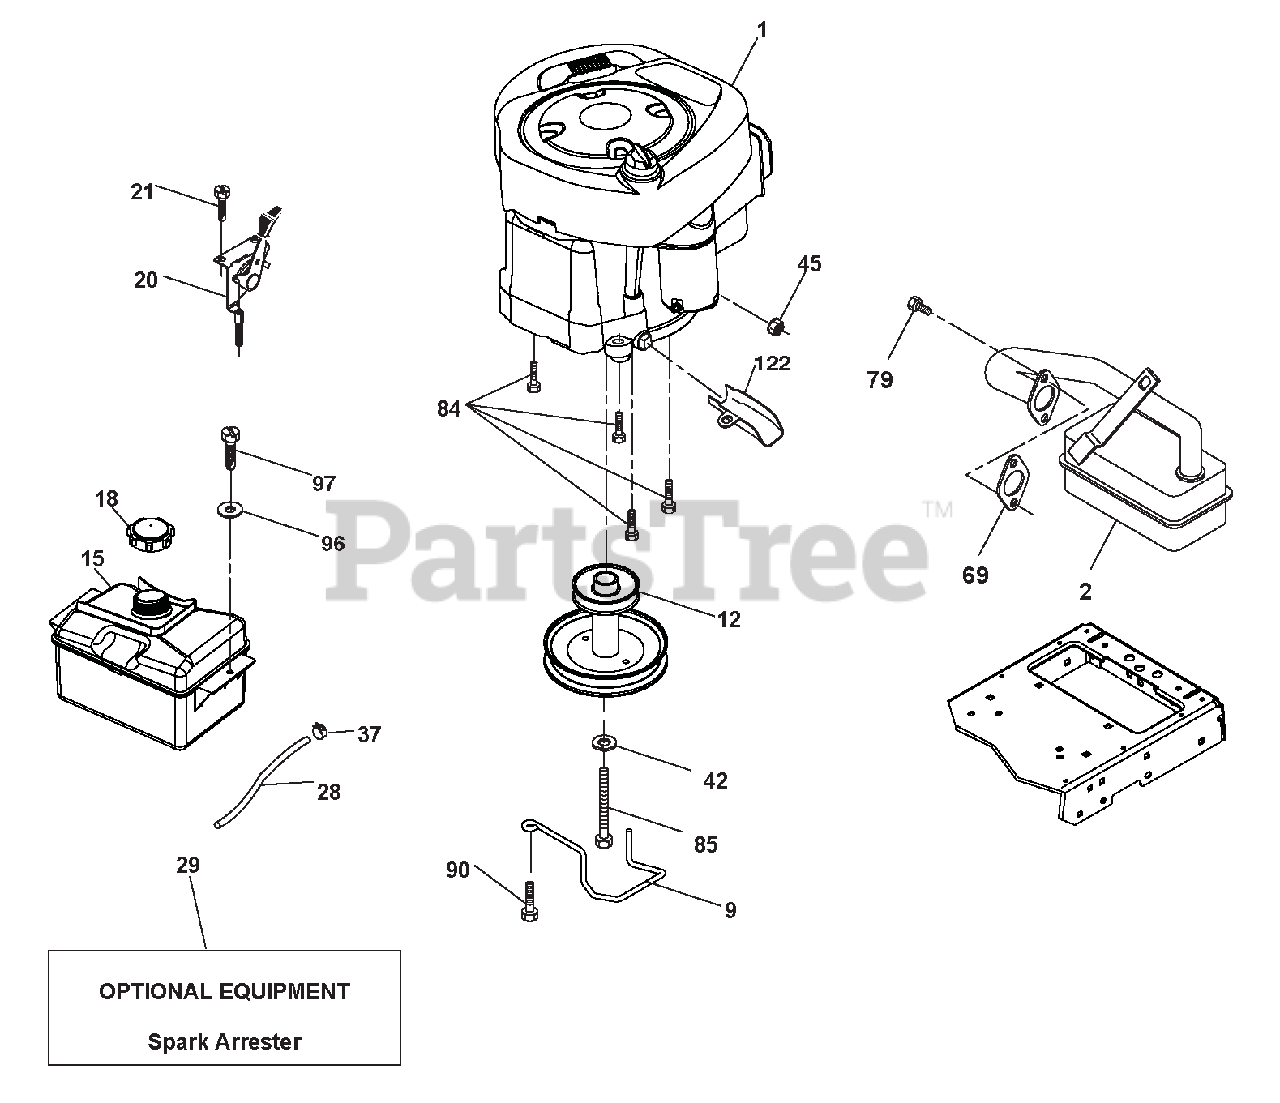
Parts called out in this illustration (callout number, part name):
1	ENGINE BRIGGS MODEL NO. 31P677-1577-G5 (442254)(ORDER PARTS FROM ENGINE MANUFACTURER.)
2	Muffler Exhaust B&S
9	KEEPER BELT ENGINE
12	PULLEY.ENGINE
15	TANK FUEL
18	CAP FUEL
20	CONTROL.THROTTLE
28	LINE.FUEL.20"
29	KIT.SPARK ARRESTOR(392390 B&S)
37	CLAMP.HOSE.BLK.
42	WASHER.LOCK.HVY HLCL.SPR.7/16
45	Nut, Keps Hex 1/4-20 unc
69	Gasket Eng 1 313 Id Tin Plated
79	SCREW.SOCKET HD.5/16-18 X .75
84	Screw 3/8-16 x <
85	BOLT.HEX.7/16-20X4XGR5-1.5THR.
90	SCREW.3/8-16X1.SMGML.TAP/R.BLK
96	WASHER.9/32 X 7/8 X 16GA.
97	SCREW.HEXWSH.THDROL.1/4-20X3/4
122	Extension Drain Oil
